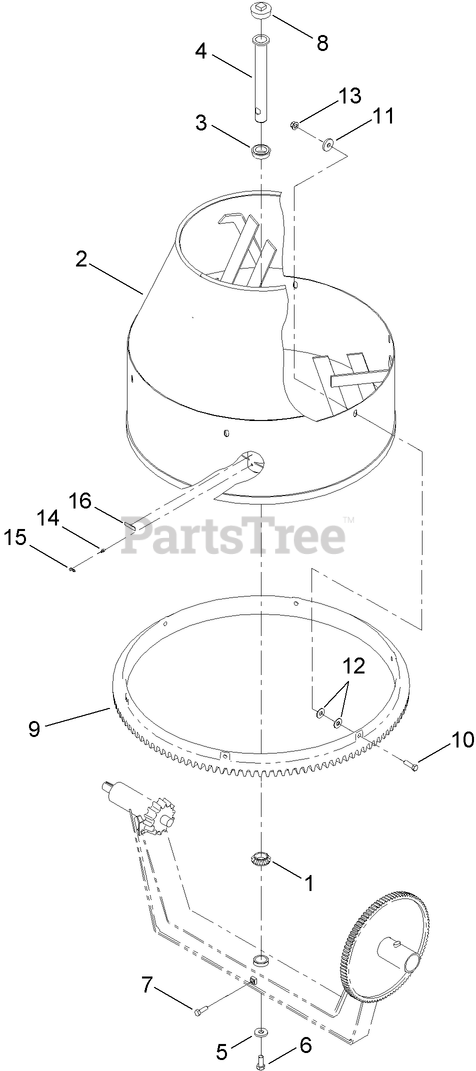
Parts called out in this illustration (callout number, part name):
1	BEARING-ROLLER
3	BEARING
4	SPINDLE
5	WASHER-FLAT
6	SCREW-HH
7	SCREW-HH
9	GEAR-RING
10	SCREW-HH
11	WASHER-FLAT
12	WASHER-FLAT
13	NUT-LOCK
14	FITTING
15	CAP-PLUG
16	DECAL-GREASE
